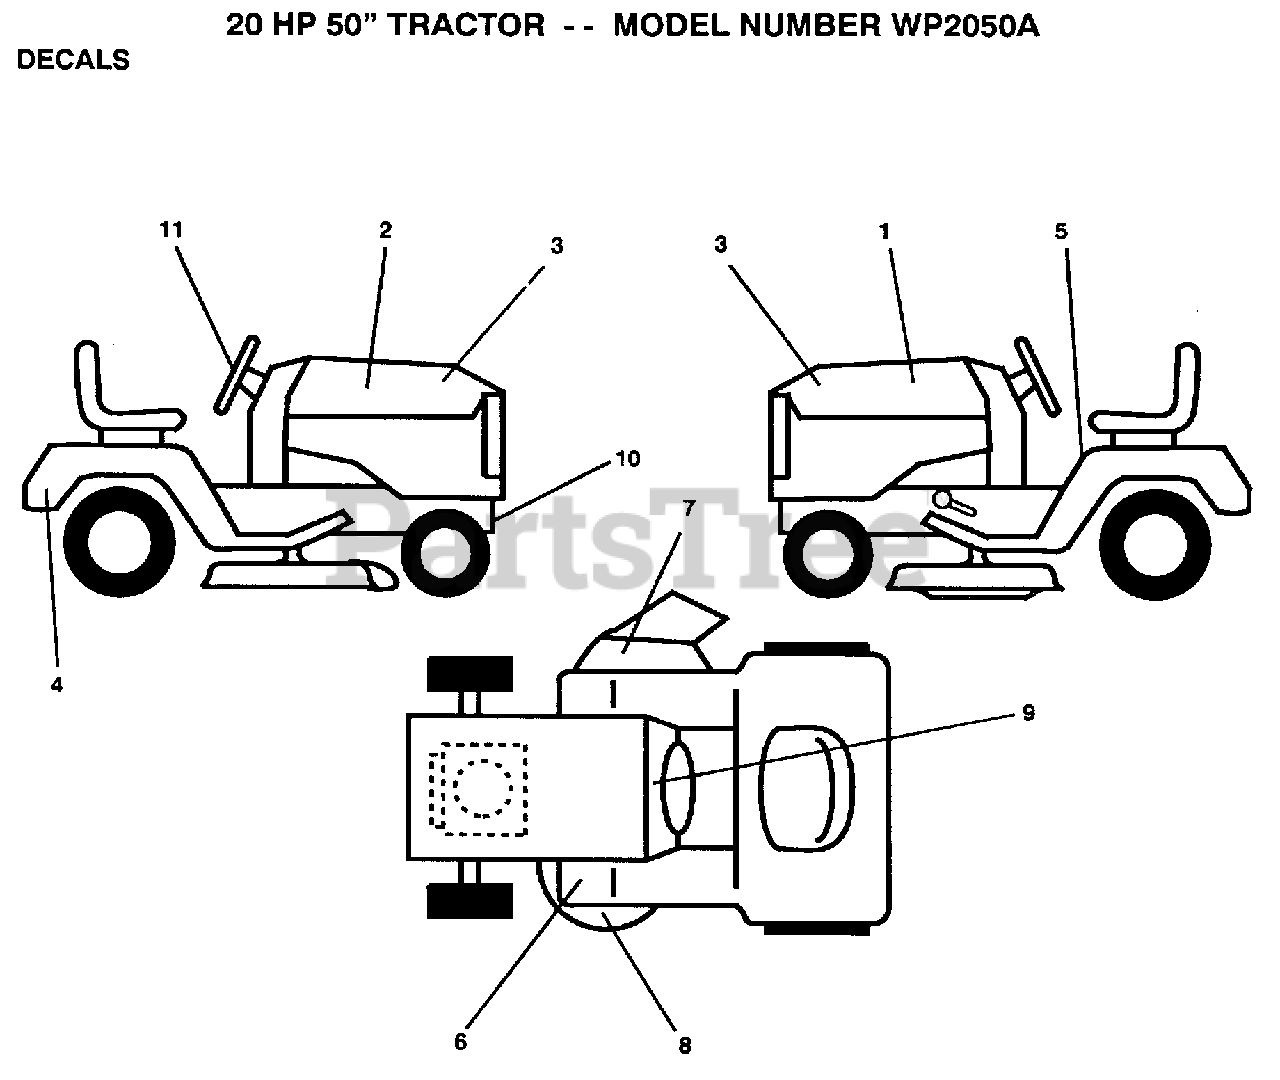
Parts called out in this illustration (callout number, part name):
1	DECAL.HOOD.LH
2	DECAL.HOOD.RH
4	DECAL, LOGO, FENDER
5	DECAL
7	DECAL WARING
8	DECAL INSTRUCTION CAUTION
11	DECAL, INSERT
